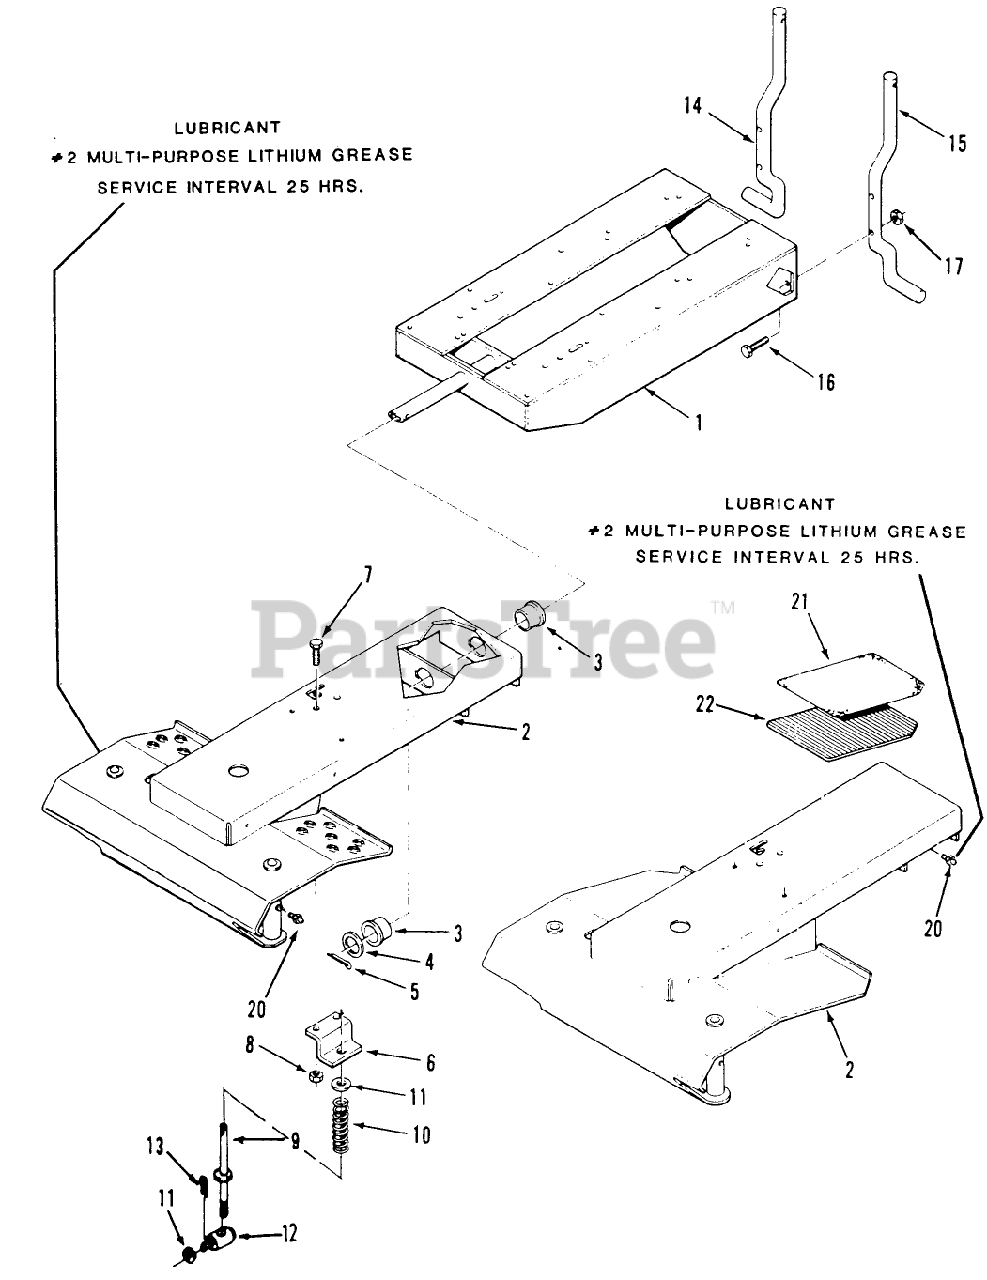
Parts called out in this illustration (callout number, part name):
1	ASS'Y-FRAME REAR *R
9	ASSY ROD
10	SPRING-COMPRESSION
14	REAR ROD RH *B
15	REAR ROD LH *B
22	PAD FOOTREST RH
